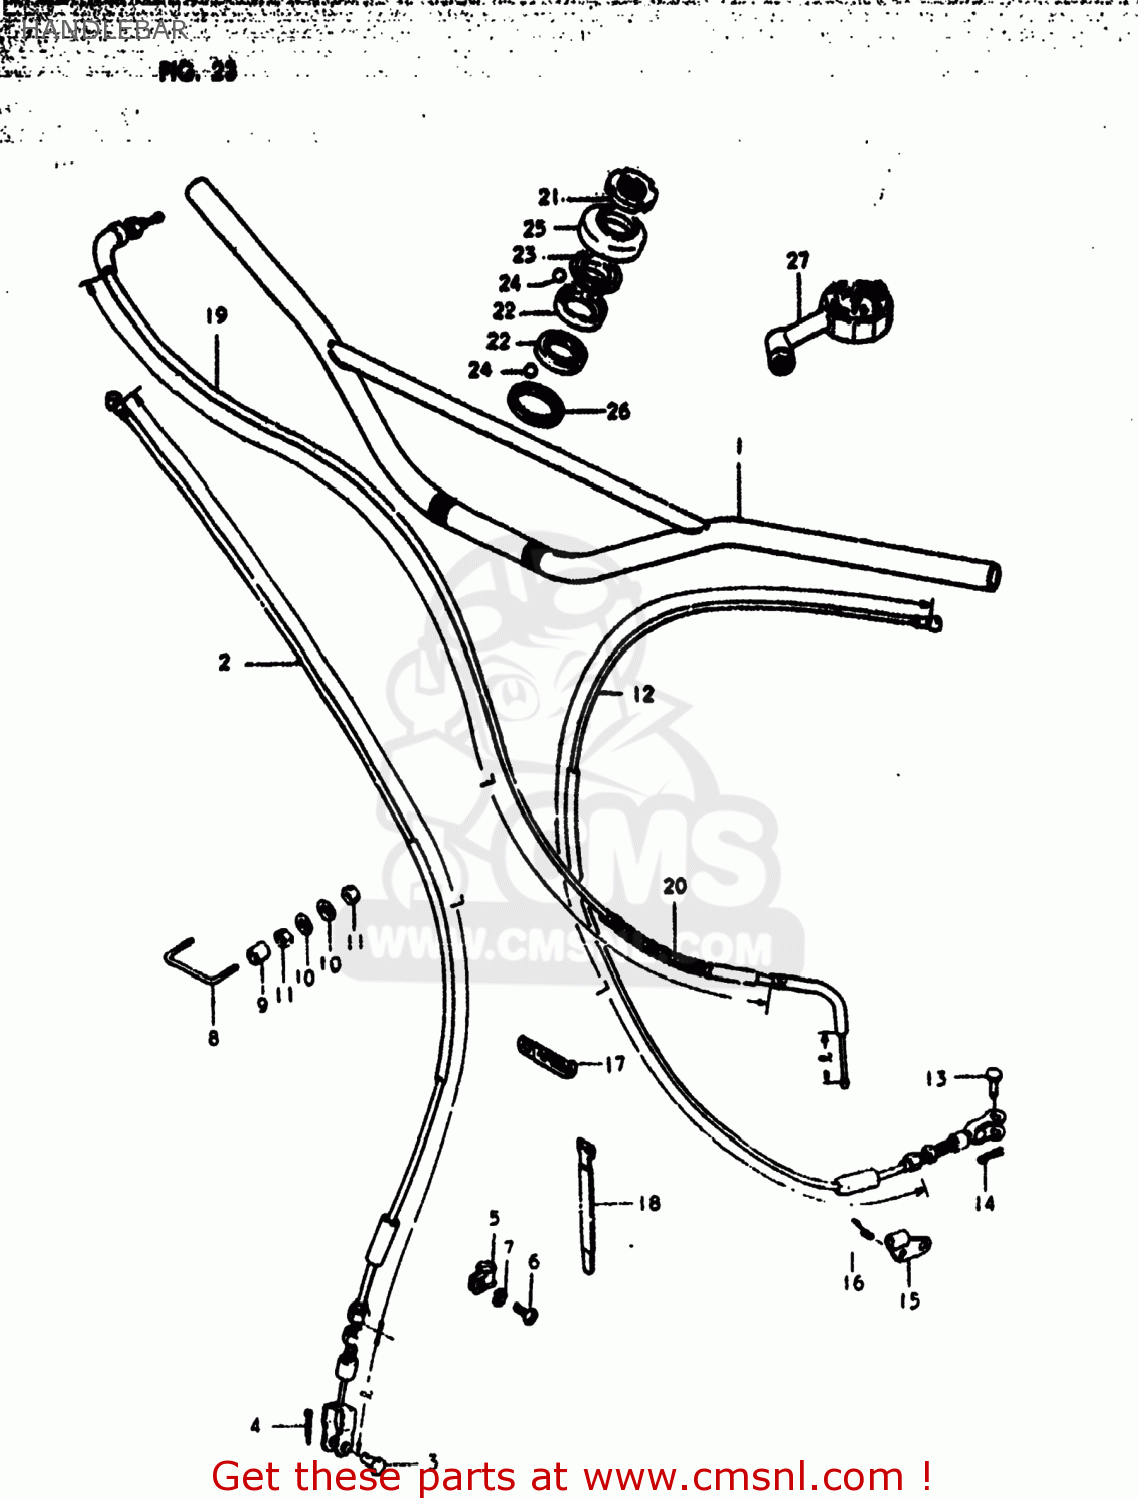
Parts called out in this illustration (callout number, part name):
1	HANDLEBAR
2	CABLE ASSEMBLY,FRONT BRAKE
3	PIN(L:17.5)
4	PIN
5	GUIDE,CABLE
6	SCREW
7	LOCK WASHER
8	CLAMP,CABLE
9	BUSHING
10	WASHER
11	NUT 3MM
12	CABLE ASSY,CLUTCH
13	PIN(L:13)
14	PIN
15	STOPPER,CLUTCH CABLE
16	SCREW
17	CLAMP L:35
18	CLAMP
19	CABLE ASSEMBLY,THROTTLE
20	PROTECTOR,CABLE
21	NUT,STEERING STEM
22	RACE,STEERING,INNER,UPPER
23	RACE,STEERING,OUTER,UPPER
24	BALL
25	SEAL,STEERING UPR DUST
26	DUST SEAL,STEERING HEAD
27	GAUGE ASSY,AIR PRESSURE
